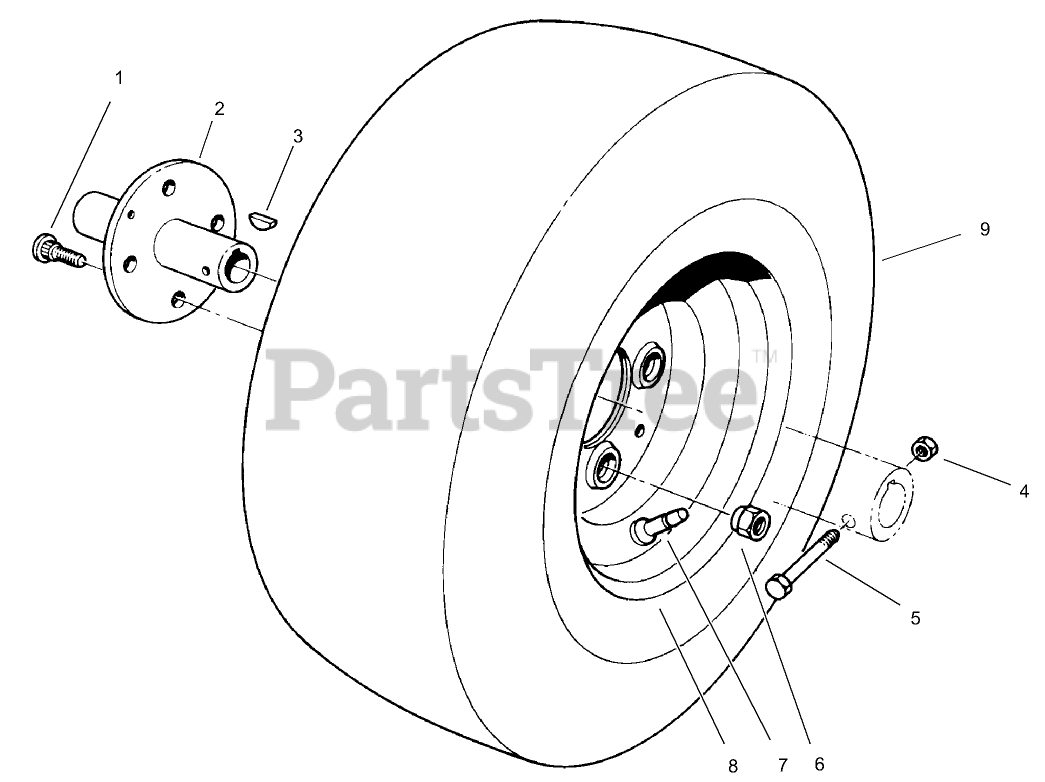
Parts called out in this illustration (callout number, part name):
1	1/2-20X1.25 BOLT
2	WHEEL HUB
3	KEY-WOODRUFF
4	NUT-LOCK, NI
5	SCREW-HH
6	NUT-LUG
7	STEM-VALVE
9	TIRE-4-Ply
